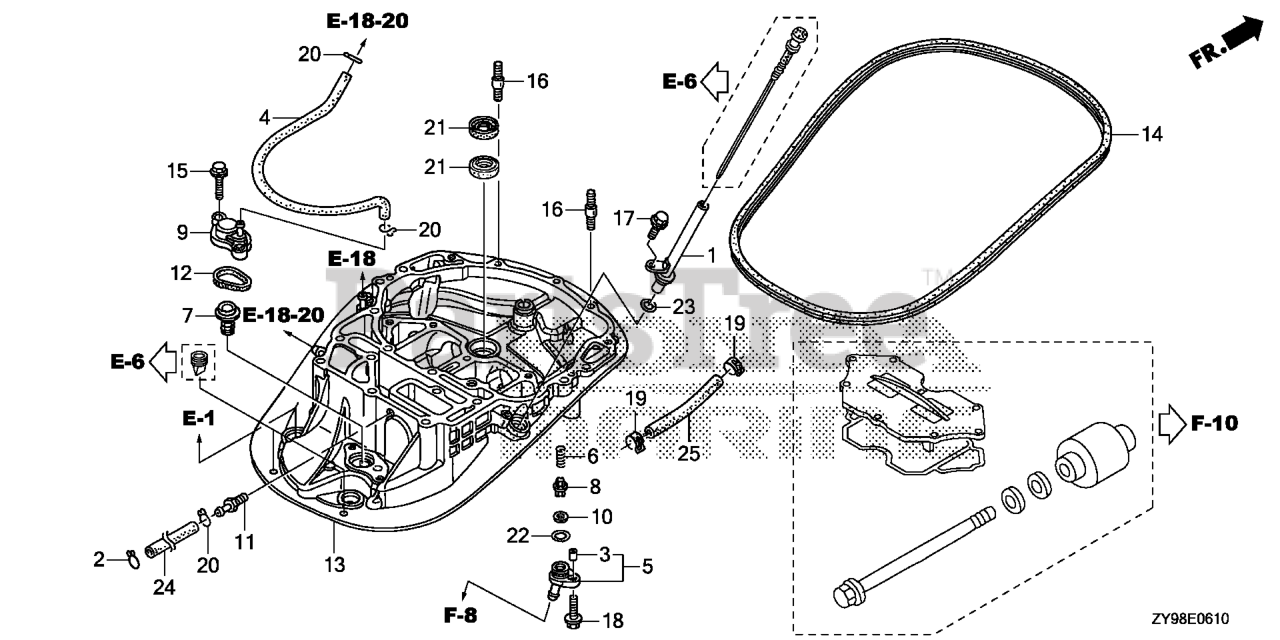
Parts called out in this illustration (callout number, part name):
1	PIPE, OIL LEVEL
2	CLIP, TUBE
3	COLLAR, DISTANCE (6.5X11X7.5)
4	TUBE B, WATER
5	COVER, FLUSH VLV
6	SPRING, FLUSH VALVE
7	VALVE ASSY., RELIEF
8	VALVE, FLUSH
9	COVER, RELIEF VALVE
10	GASKET, FLUSH VALVE
10	PKG, FLUSH VALVE
11	JOINT, WATER TUBE
12	O-RING, THERMOSTAT COVER
13	CASE, MOUNT *NH8* (DARK GRAY)
14	SEAL A, COVER (LOWER)
15	BOLT, FLANGE (6X22)
16	BOLT, STUD (8X28)
17	BOLT, FLANGE (6X12)
18	BOLT, FLANGE (6X20) (ENGINE NO.)
19	CLAMP, TUBE (D10.5) (ENGINE NO.)
20	CLIP, TUBE (B10)
21	SEAL, WATER (22X35X7)
22	O-RING (16MM)
23	O-RING (11.5X3.5)
24	TUBE, WATER CHECK
25	BULK HOSE, VACUUM (7X3000) (7X550)
